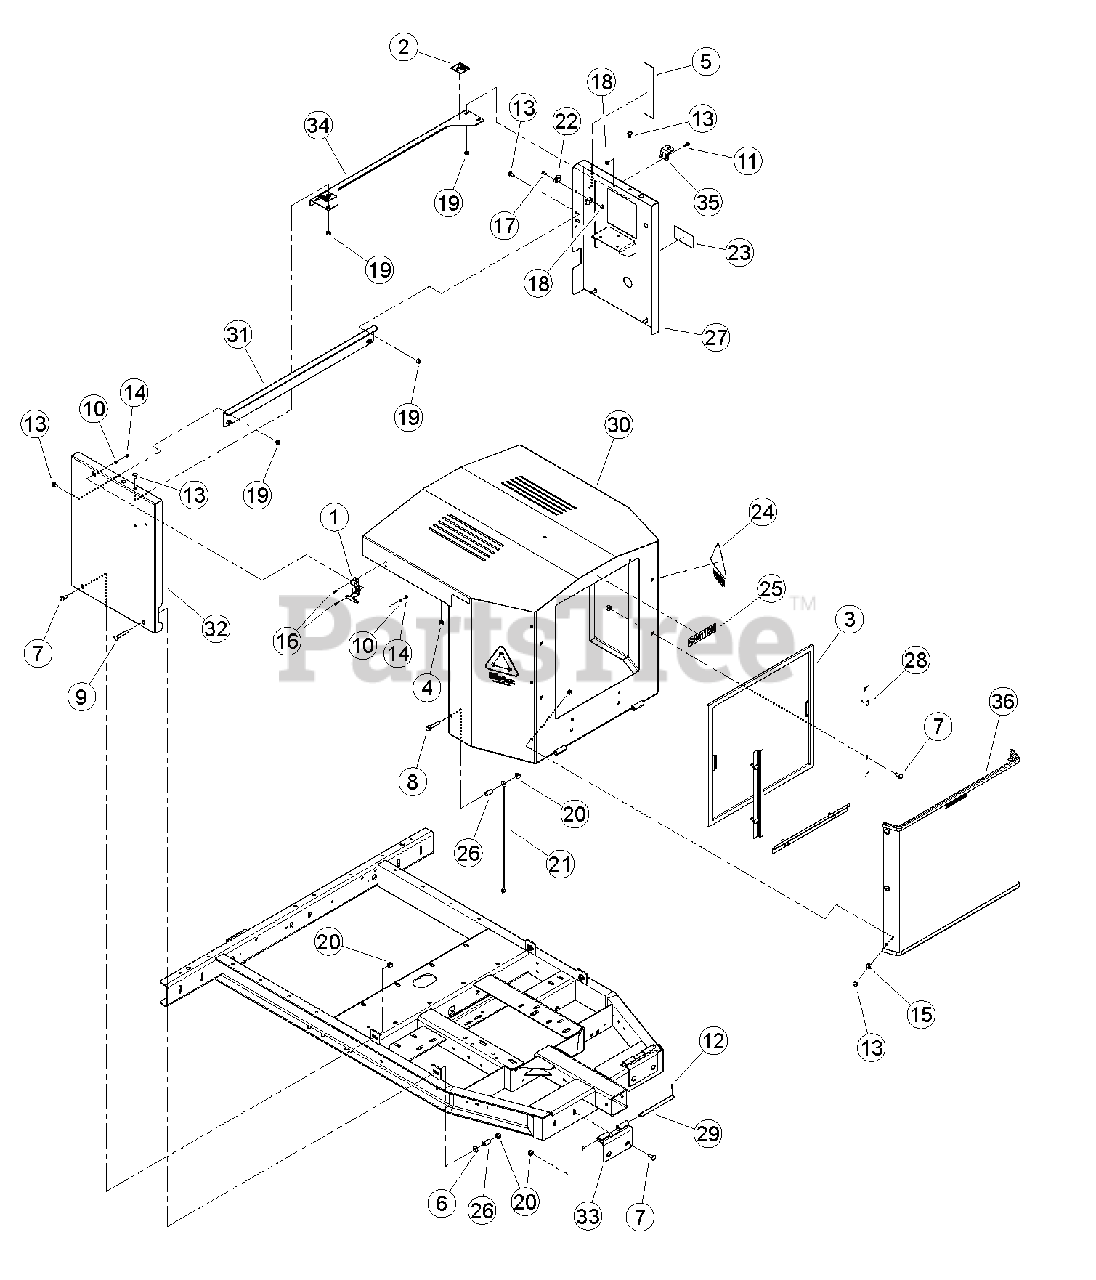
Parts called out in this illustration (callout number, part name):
1	LATCH, FLEXIBLE DRAW
2	DECAL, SHIELD DANGER ISO
3	SCREEN, RADIATOR INLET
4	BUMPER, RUBBER
5	DECAL, CHIPPER ENGAGEMENT
6	WASHER, 3/8" FLAT ZP
7	BOLT, 3/8 X 1" GR5 CRG NC ZP
8	BOLT, 3/8 X 2 FLANGE NC
9	BOLT, 3/8 X 2-1/2" GR5 CRG NC ZP
10	WASHER, 3/16" FLAT ZP
11	BOLT, 1/4 X 3/4 GR5 CRG ZP
12	ROLL PIN, 5/32 X 3/4" PLAIN
13	BOLT, 5/16 X 3/4 GR5 CRG NC ZP
14	NUT, 10/24 NYLOCK TYPE NM ZP
15	WASHER, 5/16" ID 7/8" OD NYLON FLAT
16	SCREW, MCH 10-24 X 1/2" PAN HD PH ZP
17	RIVET, AL BLIND 1/4 X 3/4 DOME HEAD
18	NUT, 1/4-20 NYLOCK-FLANGE
19	NUT, 5/16-18 NYLOCK-FLANGE
20	NUT, 3/8-16 NYLOCK FLANGE
21	LANYARD, STEEL W/ PVC 1/8 X 20"
22	CLAMP, CABLE MOUNT
23	DECAL, FEED SPEED
24	DECAL, CHIP IT
25	DECAL, MODEL CH611DH
26	IDLER SPACER
27	WELDMENT, ENGINE RIGHT
28	BRACKET, SCREEN HOLDER
29	PIN, HOOD HINGE PLATED
30	WELDMENT, 6 INCH HOOD
31	PLATE, HOOD SUPPORT
32	SHIELD, ENGINE LEFT
33	WELDMENT, HOOD HINGE
34	BRACE, ENGINE SHIELD
35	BASE, HOOD LOCK
36	ASSEMBLY, 6 INCH SCREEN
